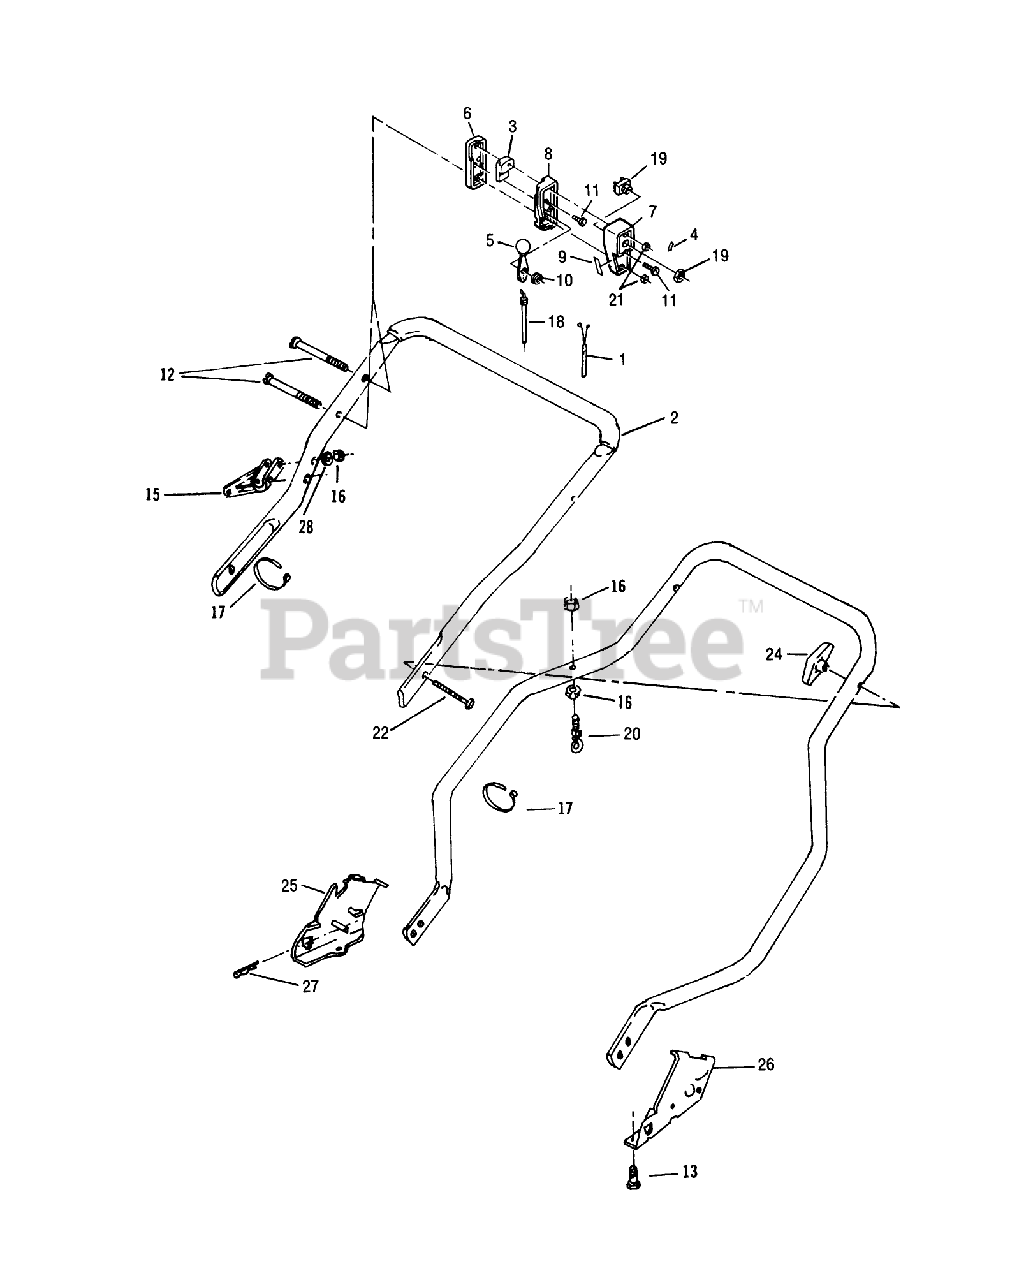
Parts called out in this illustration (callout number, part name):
5	LEVER&KNOB AY WES
10	WASHER-SPRING
11	SCREW
12	SCREW
13	SCREW
16	LOCKNUT E
18	CABLE THROT WES
20	EYE BOLT WAS MFG
21	NUT C/LOCK E
22	BOLT QUALITY
24	NUT-WING
27	HAIR PIN
28	WASHER
